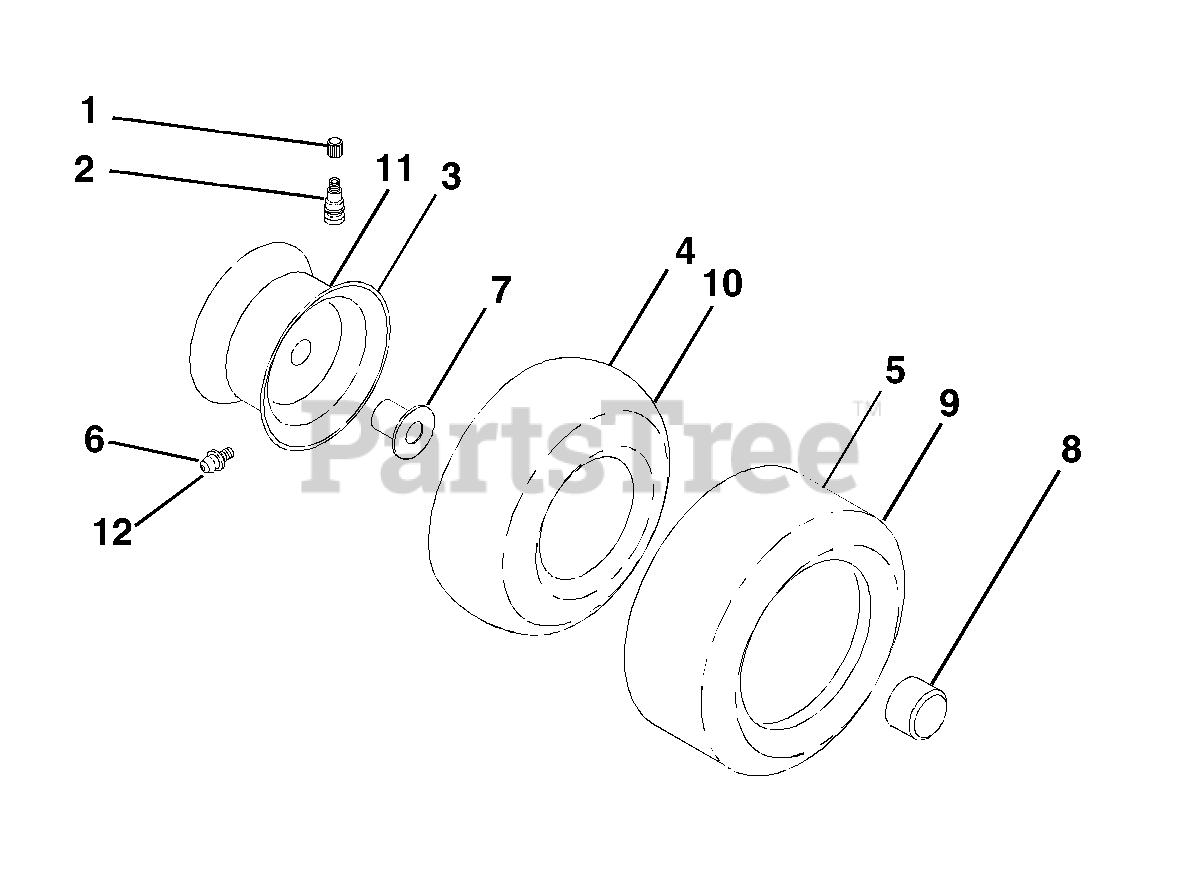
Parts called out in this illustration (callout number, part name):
1	Cap, Valve, Tire
2	Stem, Valve
3	Rim Assembly, Front
4	Tube, Front
5	Tire, Front
6	Fitting, Grease
7	Bearing, Flange
8	Cap, Axle (Front Wheel Only)
9	Tire, Rear
10	Tube, Rear
11	Rim Assembly, Rear
12	Fitting, Grease
